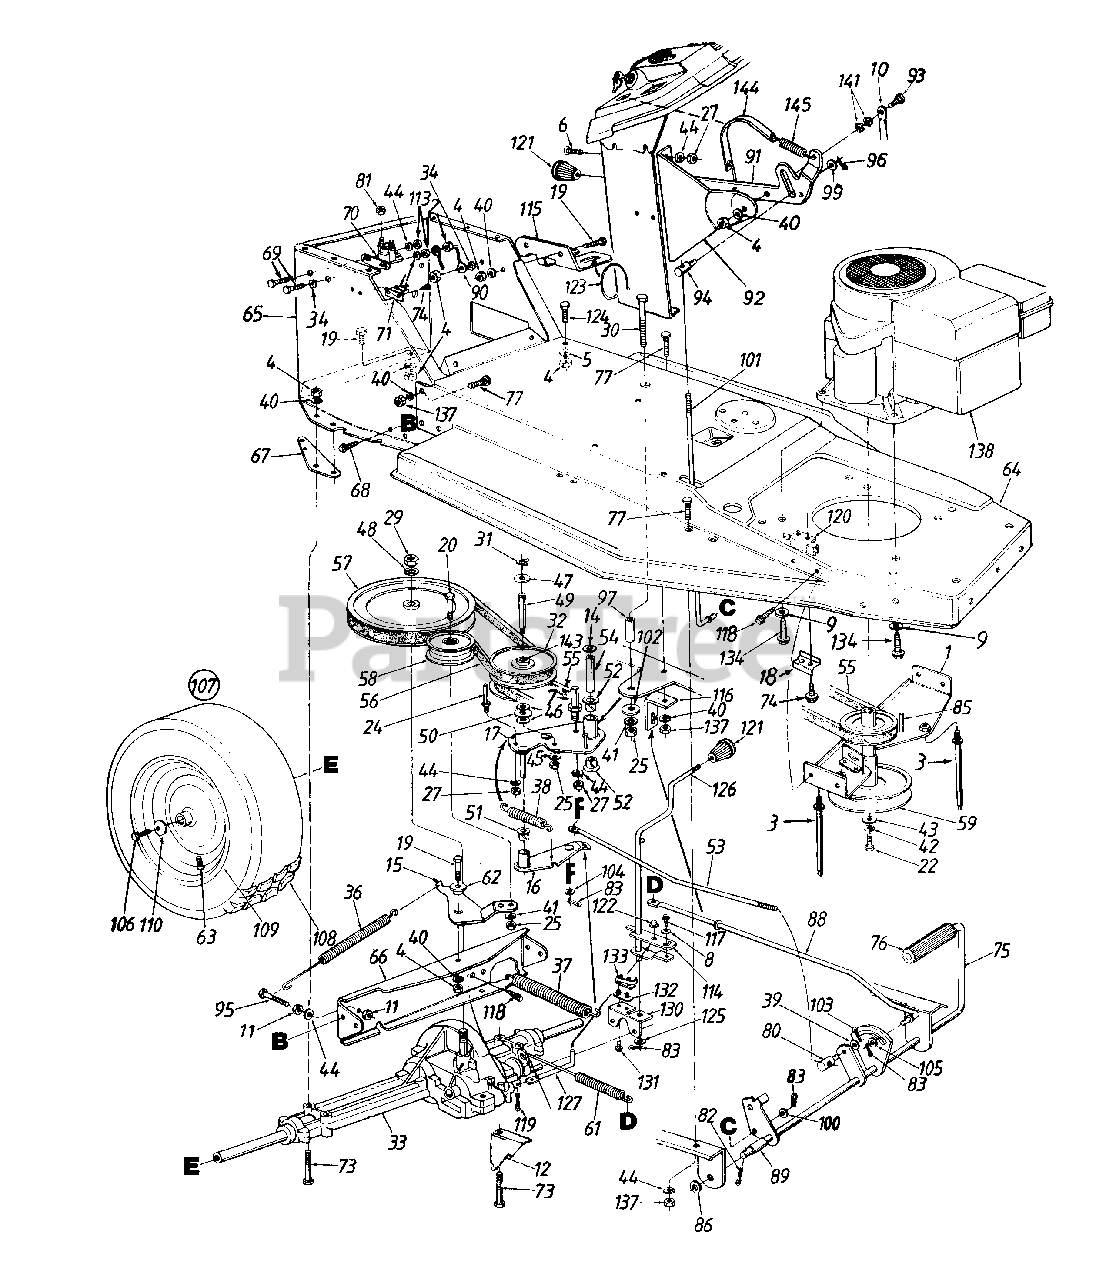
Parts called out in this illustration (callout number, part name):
1	Engine Pulley Belt Guard Ass'y.
2	Hex L-Nut 1/4-20 Thd.
3	Belt Guard Pin 5/16-18 x 4.75" Lg.
4	Hex Nut 5/16-18 Thd.
5	Bell-Wash. .345" I.D. x .88
6	Truss-Mach. Scr. 1/4-20 x .50"
7	Belt Guard Pin 1/4-20 Thd.
8	Bell-Wash. .265" I.D. x .75
9	Fl-Wash. 3/8" I.D. x .97" O.D.
10	Speed Selector Brace
11	Hex Nut 1/4-28 Thd.
14	Fl-Wash. 3/8" I.D. x 1.26" O.D.
17	Variable Speed Brkt. Ass'y.
18	Switch Plate
19	Hex Bolt 5/16-18 x .75" Lg.
20	Hex Bolt 3/8-24 x 2.0" Lg. Gr. 5
22	Hex Bolt 7/16-20 x 1.5" Lg.
24	Belt Guard Pin
25	Hex Nut 3/8-24 Thd.
27	Hex Nut 1/4-20 Thd.
29	Hex Jam Nut 9/16-18 Thd.
30	Hex Bolt 3/8-24 x 3.75" Lg.
31	Snap Ring
32	Variable Speed Pulley Ass'y.
33	Transaxle Ass'y. Comp.
34	Ext. L-Wash. 5/16" I.D.
36	Extension Spring 6.12" Lg.
37	Extension Spring 6.74" Lg.
38	Extension Spring 2.59" Lg.
39	Fl-Wash. .385" I.D. x .620"
40	L-Wash. 5/16" I.D.
41	L-Wash. 3/8" I.D.
42	L-Wash. 7/16" I.D.
43	Fl-Wash..450" I.D. x 1.25"
44	L-Wash. 1/4" I.D.
45	Bell-Wash. .39" I.D. x 1.13"
46	Fl-Wash. .56" I.D. x 1.0" O.D.
47	Washer "Teflon" .565 I.D.
48	Bell-Wash. 9/16" I.D. x 1.125" O.D.
49	Shaft .56" Dia. x 3.875" Lg.
50	Thrust Brg. 1.25 O.D.
51	Flanged Nyliner Brg.
52	Nyliner Flanged Brg.
53	Speed Control Rod
55	V-Belt
56	V-Belt
57	V-Pulley 8" Dia.
58	Idler Pulley 3-1/8" Dia.
59	Dbl. Pulley 6.0" Dia. x 3.56"
61	Extension Spring 7.08" Lg.
62	Shld. Spacer .500" Dia.
63	Air Valve
69	Hex Bolt 1/4-20 x .62" Lg.
70	Solenoid
71	Circuit Breaker
73	Hex Bolt 5/16-18 x 2.75" Lg.
74	Truss Mach. B-Tap Scr. #10 x .50" Lg.
77	Ribbed Neck Bolt 5/16-24 x .84"
80	Ferrule
81	Hex Sems Nut 1/4-20 Thd.
82	Cot-Pin 1/8" Dia. x 1.25" Lg.
83	Cot-Pin 3/32" Dia. x .75" Lg.
85	Sq. Key 1/4 x 2.0" Lg.
86	Fl-Wash. .635" I.D. x 1.0"
89	Spacer 5/8" I.D. x 1.2" Lg.
90	Ground Wire 7.25" Lg.
91	Speed Selector Lever
92	7 Speed Selector Brkt.
93	Shld. Bolt .437" Dia. x .47" Lg.
94	Ferrule
95	Hex Bolt 1/4-28 x 1.25" Lg.
96	Intern. Cot-Pin 5/16" Dia.
97	Spacer .375" I.D. x .625"
99	Fl-Wash. .344" 1.0. x .62"
100	Fl-Wash. .25" I.D. x .62" O.D.
101	Speed Control Rod
102	Fl-Wash. 3/8" I.D. x 1.25" O.D.
103	Cot-Pin 1/8" Dia. x 1.0" Lg.
104	Fl-Wash.. 34" I.D. x .68"
105	Fl-Wash. .34" I.D.
106	Hex L-Bolt 5/16-24 x .75" Lg.
110	Bell-Wash. .345" I.D. x .88"
113	Hex Jam Nut 1/4-20 Thd.
114	Shift Lever Adjusting Link
115	Shift Lever Spring Brkt.
118	Hex Wash. Hd. Tap Scr. 1/4-20 x .5" Lg.
119	Intern. Cotter Pin
120	Safety Switch (Clutch)
121	Knob
122	Retaining Ring
123	Compression Spring 1.5" Lg.
124	Hex Wash. Hd. Scr. 5/16-18 x 7/8" Lg.
125	Fl-Wash. .469" I.D. x .88"
130	Shift Lever Support
131	Hex Wash. Hd. #8 x .50" Lg.
132	Insulator Nut Plate
133	Spring Switch
134	Hex Tap Scr. 3/8-16 x 1.25"
137	Hex Nut 5/16-24 Thd.
138	Engine
141	Wave Wash. .445" I.D.
144	7-Speed Indicator Strip
145	Ext. Spring 2.04" Lg. (Style 0, 1)
